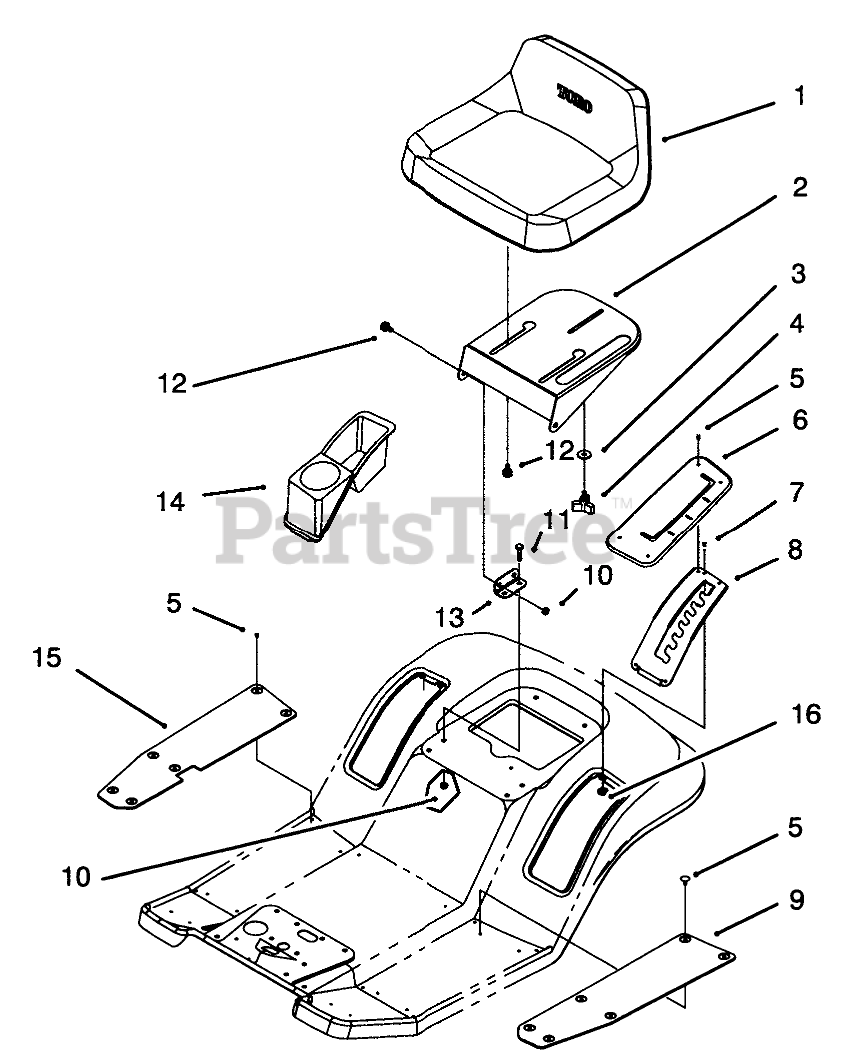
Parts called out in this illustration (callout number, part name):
1	SEAT
2	Support-Seat
3	WASHER-PIVOT
5	FASTENER-PANEL
6	COVER-HOC
7	RIVET-BLIND
8	Gate-H.O.C.
9	MAT-FOOT, LH
10	NUT-LOCK, NI
11	SCREW-HH
12	BOLT-SHOULDER
13	Bracket-Seat Hinge
14	TRAY-FENDER
15	MAT-FOOT, RH
16	WASHER-PLAIN
